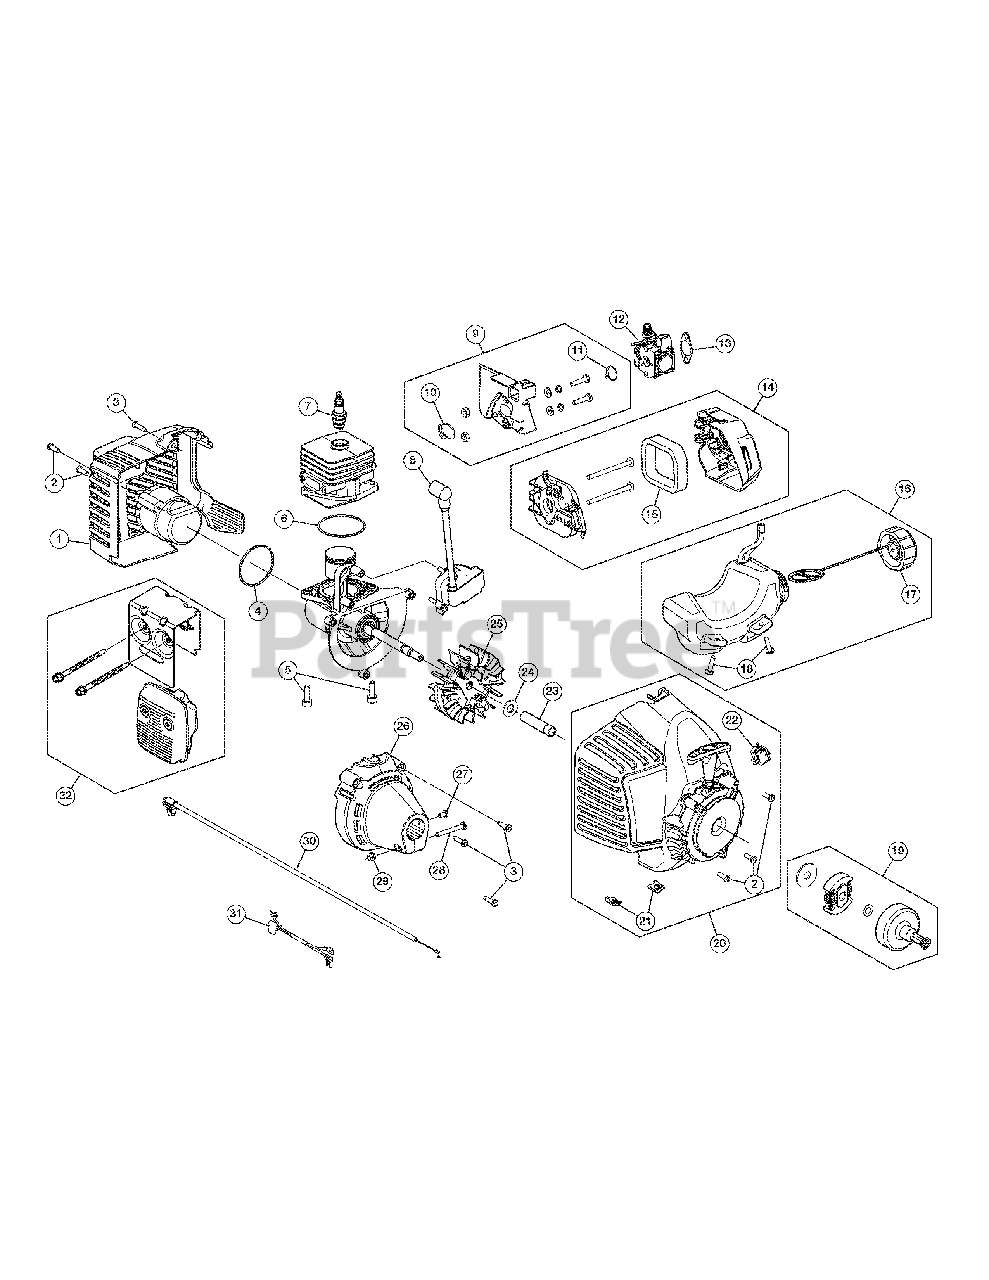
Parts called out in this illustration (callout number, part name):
1	Rear Cover Assembly (Incl. 2 & 3)
2	Housing Screw
3	Cover Screw
4	O-Ring
5	Crankcase Bolt
6	Crankcase O-Ring
7	Spark Plug
8	Module Assembly
9	Insulator Assembly (Incl. 10 & 11)
10	Insulator O-Ring
11	Carburetor O-Ring
12	Carburetor
13	Air Cleaner Gasket
14	Aircleaner Cover Assembly (Incl. 15)
15	Aircleaner Filter
16	Fuel Tank Assembly (Incl. 17 & 18)
17	Fuel Tank Cap
18	Fuel Tank Screw
19	Starter Clutch Assembly
20	Starter Housing (Incl. 2, 21 & 22)
21	U-shaped Nut
22	Switch Assembly
23	Spacer
24	Washer
25	Flywheel Assembly
26	Clutch Cover (Incl. 3)
27	Anti-rotation Screw
28	Clamp Screw
29	Clamp Nut
30	Throttle Cable
31	Lead Wires
32	Muffler Assembly
